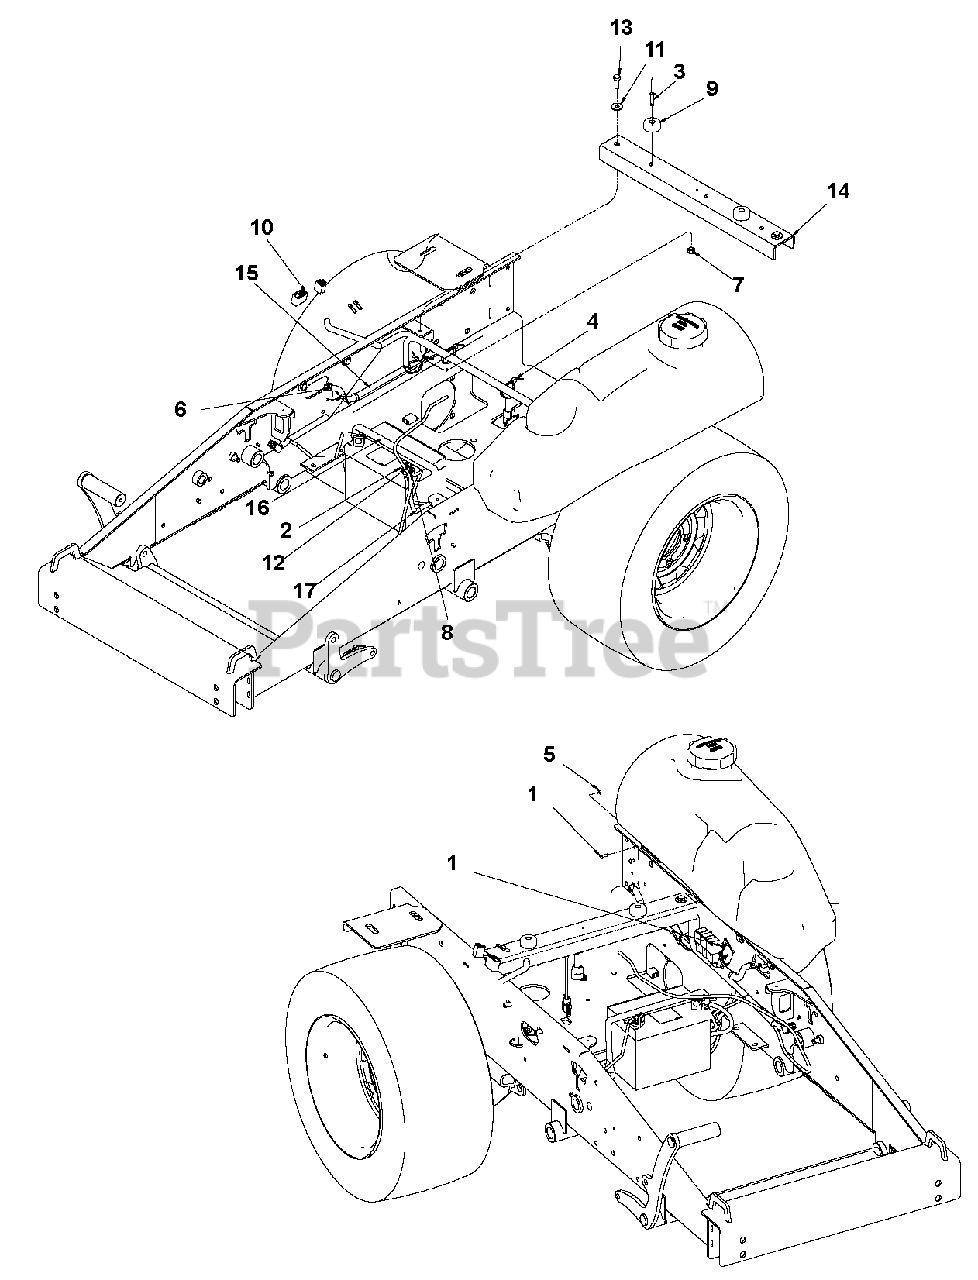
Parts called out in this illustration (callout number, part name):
1	Screw, 10-24 x .625 PAN PHL MAC
2	Bolt, 5/16-18 x .750 CR G 5
3	Rivet, 3/16 x .500 Pop
4	Cable Tie, .15 x 8.50
5	Nut, 10-24 KEPS
6	Clamp, 1/2 Spring Hose
7	Locknut, 3/8-16 Crown
8	Nut, 5/16-18 Hex Grade 5
9	Bumper, Rubber .625 x 1.50 DIA
10	Harness, Power Unit Wire
11	Washer, .375 REG Flat
12	Washer, .313 MED Spring Lock
13	Bolt, 3/8-16 x 1.00 Hex 5
14	Plate, Top Crossmember
15	Assembly, Fuel Line
16	Band, 15'' Rubber Bungee
17	Cabe, Battery - 35" Positive
